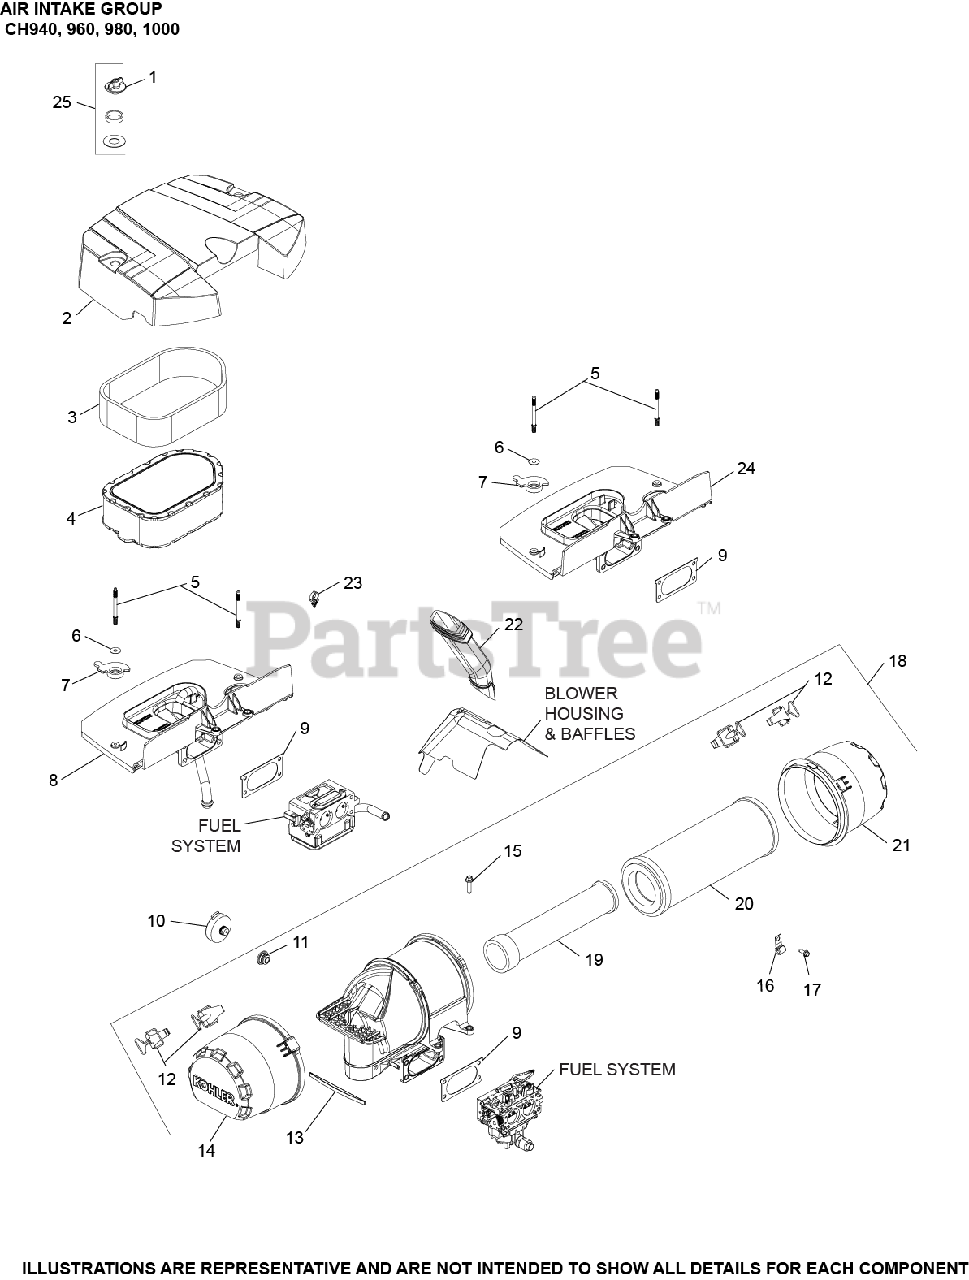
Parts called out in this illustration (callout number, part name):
9	GASKET, AIR CLEANER ELBOW
10	SENSOR, FILTER REPLACEMENT
11	PLUG, HOLE
12	CLIP ASSEMBLY
13	DAMPER, FOAM INSERT
14	COVER, RAIN CAP
15	SCREW, FLG M6X1.0X25
17	SCREW, THREAD FORMING
18	KIT, AIR CLEANER
19	ELEMENT, AIR FILTER - SAFETY
20	ELEMENT, AIR FILTER - PRIMARY
21	COVER, AIR FILTER
